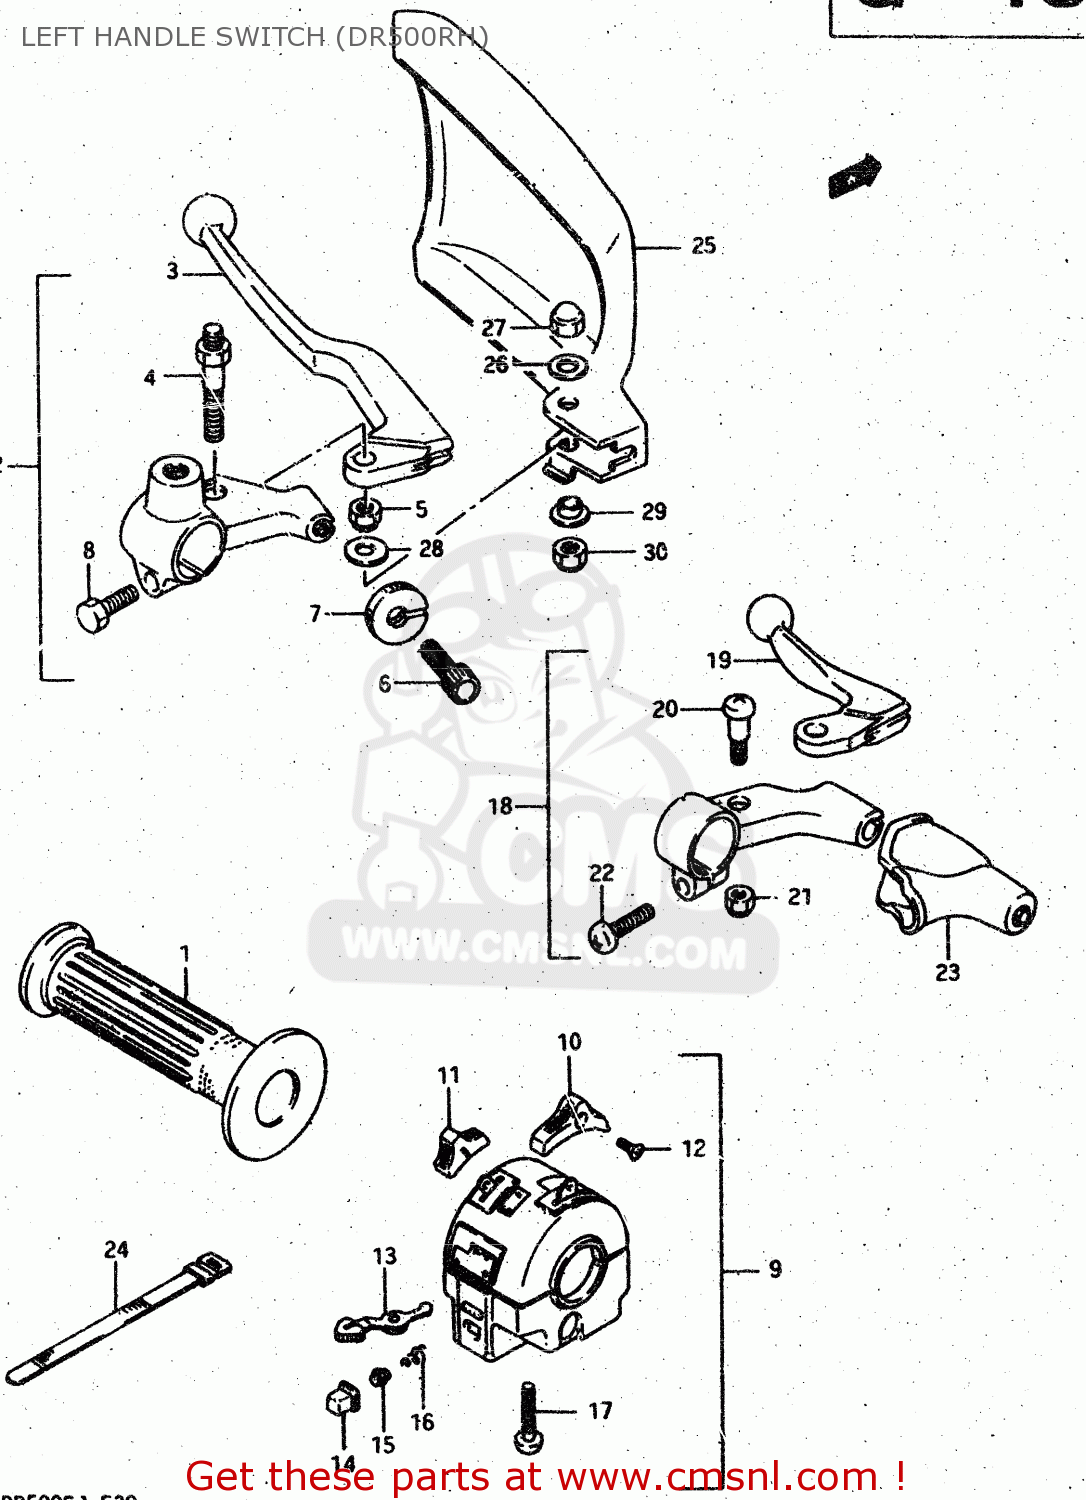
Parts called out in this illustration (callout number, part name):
1	GRIP,L
2	LEVER ASSY, CLUTCH
3	LEVER,CLUTCH
4	BOLT
5	NUT
6	ADJUSTER,CABLE
7	NUT,CABLE ADJUSTER LOCK
8	BOLT
9	SWITCH ASSY,HANDLE LH
10	KNOB,LIGHTING SWITCH
11	KNOB,DIMMER SWITCH
12	SCREW
13	KNOB,TURNSIGNAL
14	BUTTON,HORN
15	CONTACT
16	SPRING
17	SCREW
18	LEVER ASSEMBLY,DECOMPRESSION
19	LEVER,DECOMP
20	BOLT,LEVER
21	NUT
22	SCREW
23	COVER,DECOMP LEVER DUST
24	CLAMP(L:120)
25	GUARD, KNUCKLE, LH (WHITE)
26	WASHER (6.5X20X1.6)
27	NUT 6MM
28	WASHER(6.5X16X1.2)
29	WASHER
30	NUT 6MM
